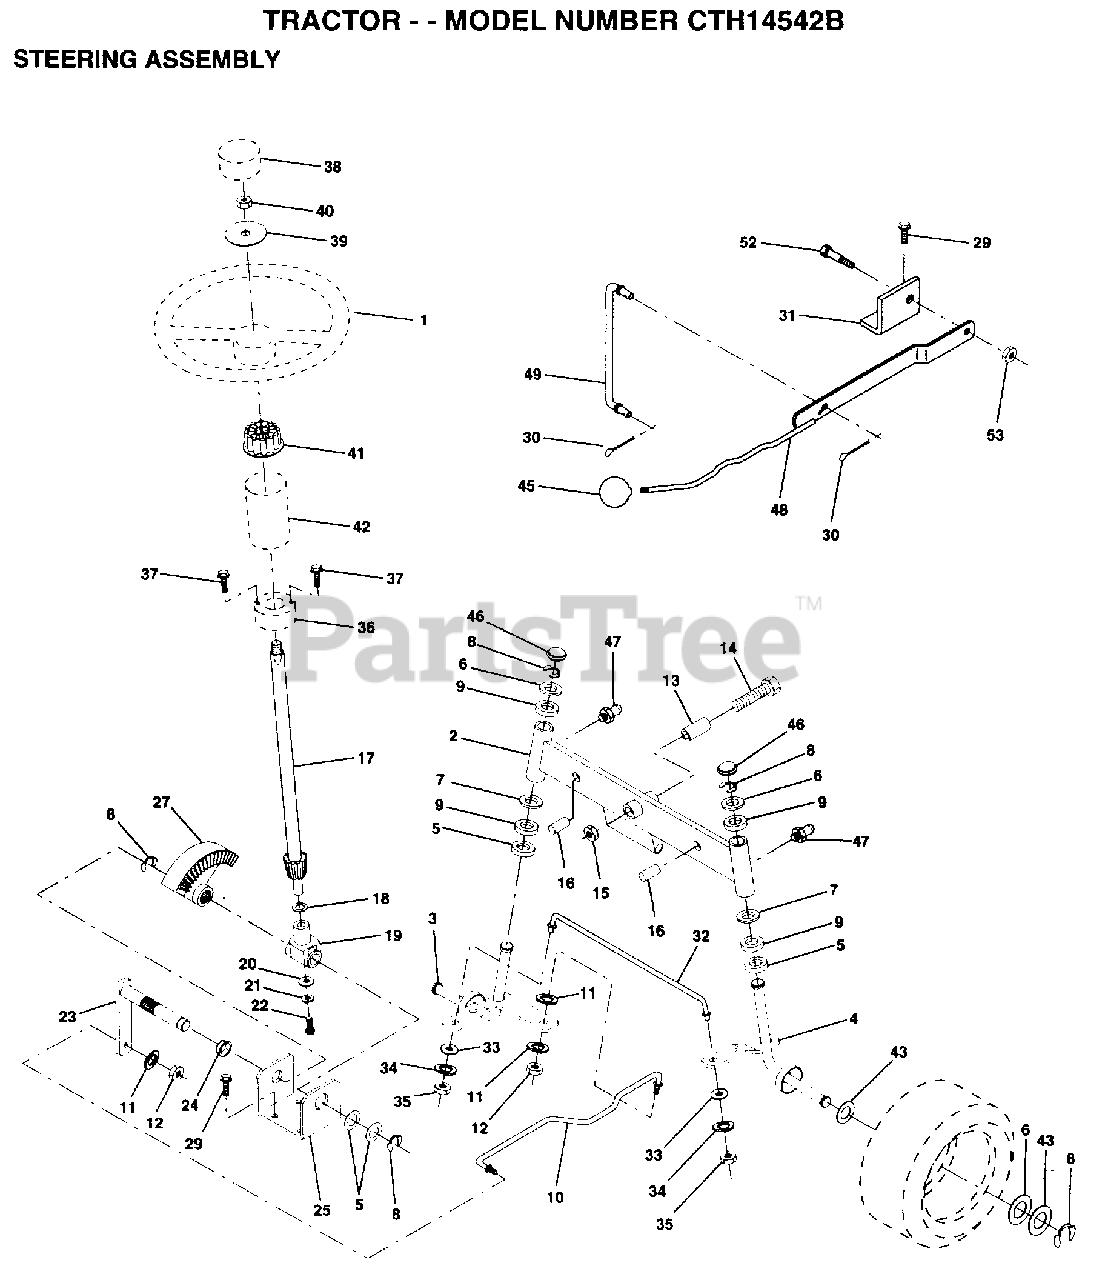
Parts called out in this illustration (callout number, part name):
1	WHEEL STR AYP BLK
2	AXLE ASM FRONT
3	SPINDLE LH
3	COL. SRTG. BEAR.
4	SPINDLE RH
5	WASHER .T
6	WASHER
7	WASHER
8	RING
11	LOCKWASHER
13	BEARING
14	BOLT HEX 5/8-11
15	"NUT-LOC,FLANGE LT"
16	AXLE PIN
17	STEERING SHAFT
18	THRUST WASHER
19	SUPPORT.SHAFT
21	LOCKWASHER
22	SCREW.SCKTHD.CAP
24	NYLINER T
25	"BRKT,STEERING"
27	GEAR SECTOR
29	SCREW
30	COTTER PIN
31	BRKT.PVT.MAN.LVR.
32	ROD.TIE.19.75
33	WASHER M
34	LOCKWASHER
35	NUT.LOCK.5/16-24
36	BUSHING.STRG.3/4
37	SCREW.10-24X1/2
38	CAP STEER AYP
39	WASHER
41	ADAPTER LT
42	BOOT SHAFT STEER
43	WASHER
45	CONTROL KNOB LT
46	CAP
47	ZERK M
48	LEVER.ASM.CLUTCH
49	LINK CLTCH W/NUTS
52	"BOLT, SHOULDER LT"
